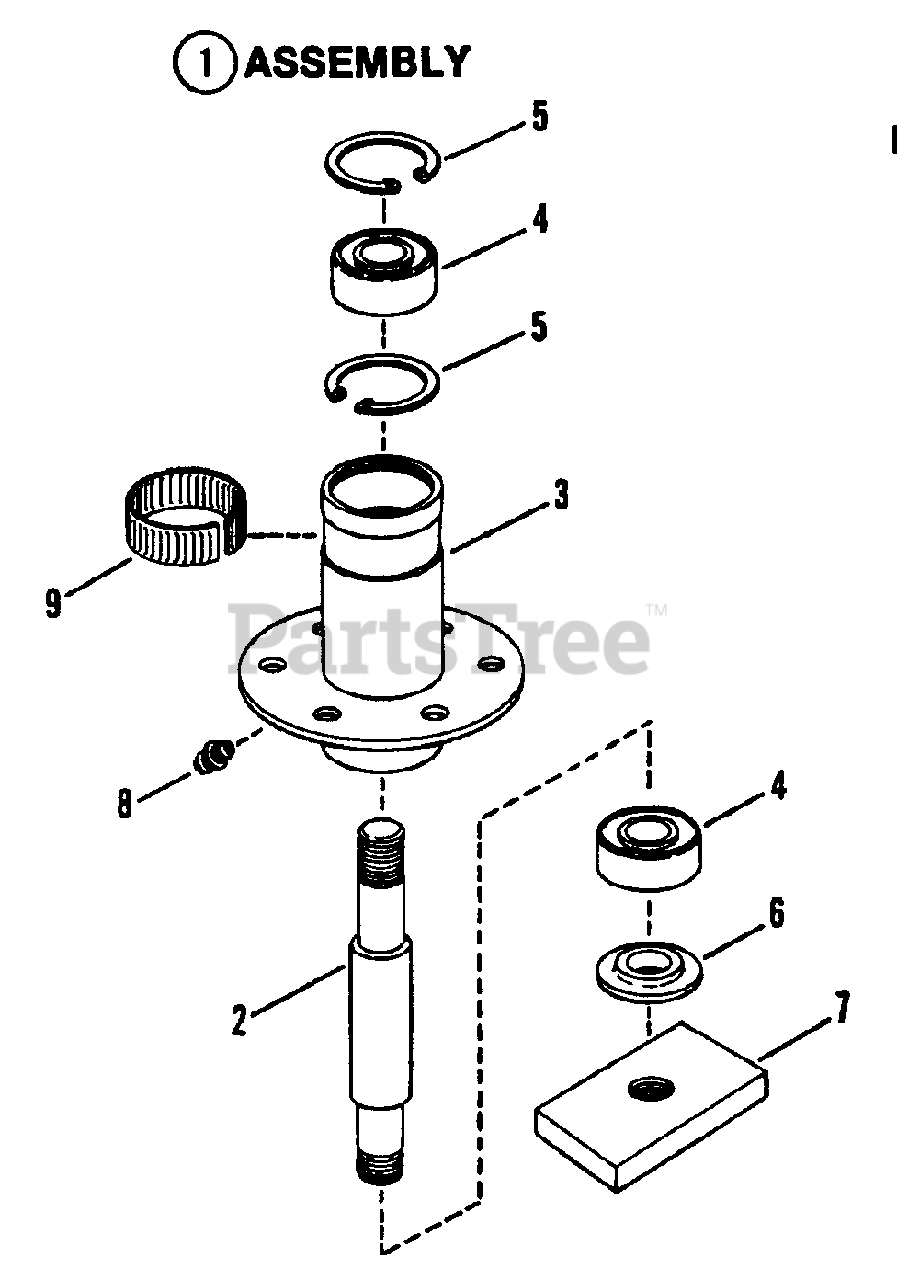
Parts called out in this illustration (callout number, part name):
1	ASSEMBLY, Spindle
2	SPINDLE, 7.25"
3	HOUSING, Spindle
4	BEARING, Spindle
5	RING, Retaining
6	WASHER, Spindle
7	HOLDER, Blade
8	FITTING, Lube (Press fit for .187 hole-no ball)
9	RING, Tolerance
